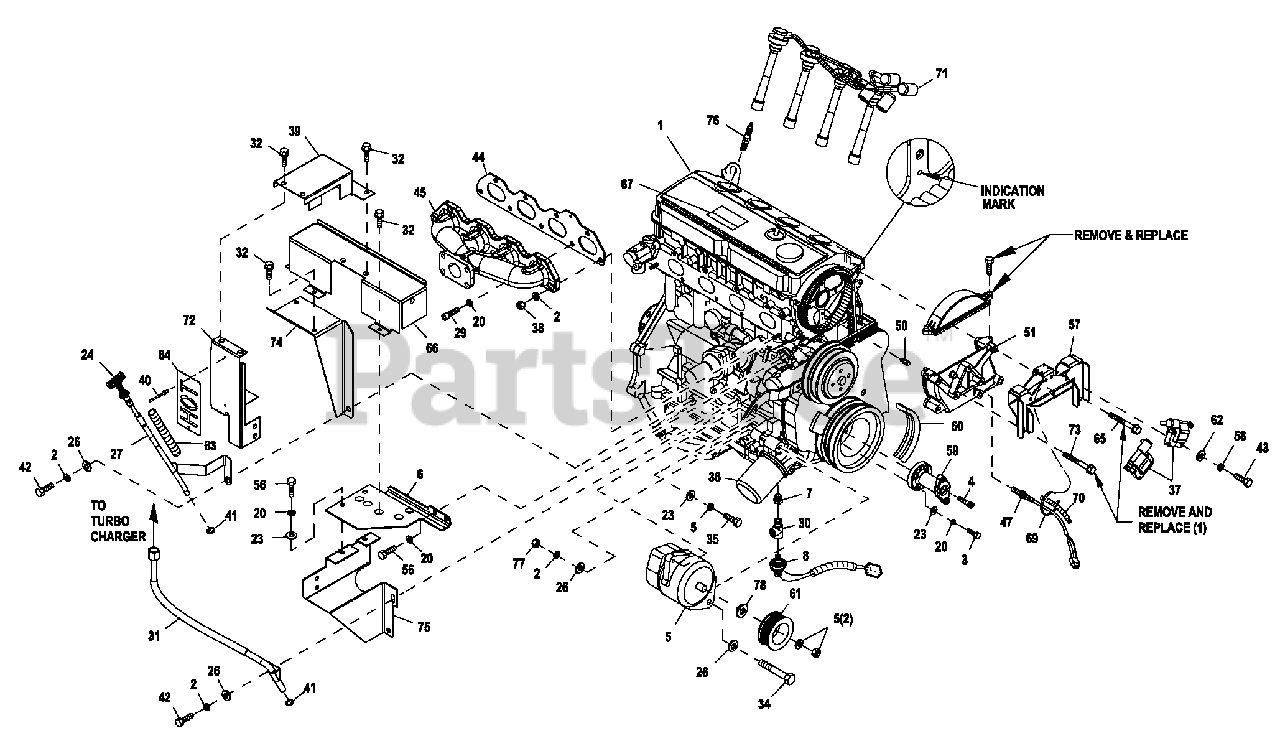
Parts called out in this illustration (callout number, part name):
1	ENGINE 2.4L G2 CERTIFIED
2	WASHER LOCK M10
3	SCREW HHC M8-1.25 X 35 G8.8
4	SCREW SHC M14-1.5 X 35 G10.9
5	ALTERNATOR DC W/O U T P ULLEY
6	U PR BRKT HEAT SHIELD 2.4L 36KW
7	ADAPTOR 1/8NPTF TO 1/8BSPT
8	SWITCH OIL PRESSU RE 10 PSI 2 POL (R-PANEL)
20	WASHER LOCK M8-5/16
23	WASHER FLAT 5/16-M8 ZINC
24	ASSEMBLY DIPSTICK G2.4L
26	WASHER FLAT 3/8-M10 ZINC
27	ASSY DIPSTICK TU BE 2.4 G2
29	SCREW SHC M8-1.25 X 25 G12.9
30	TEE STREET 1/8NPT BRASS W/VS
31	TU BE TU RBO OIL RETURN G2 36KW
32	SCREW HHTT M6-1.0 X 12 ZINC
34	SCREW HHC M10-1.5 X 120 C8.8
35	SCREW HHC M8-1.25 X 25 G10.9
36	FILTER 1.5L/2.4L G2 OIL
37	COIL-2.4L G2 IGNITION
38	N U T HEX M10-1.25 G8 YEL CHR
39	HEAT SHEILD INNER 2.4L G2 36K
40	RIVET POP .125 X 0.337 STEEL
41	O-RING SIZE 9.0MM X 2.0MM NITR
42	SCREW HHC M10-1.25 X 20 C8.8
43	SCREW HHM #10-32 X 1-1/4
44	GASKET EXHAU ST MANIFOLD
47	ASSY MAGPICK U P(3/8-24 MALE)
48	ADAPTER ENGINE 2.4L MACHINE
51	COVER CAM GEAR G2 REWORKED
56	SCREW HHC M8-1.25 X 16 C8.8
57	BRACKET ASM-2.4L COIL G2
58	WASHER LOCK #10
59	ADAPTER 2.4L CRANKSHAFT MACH
60	BELT SERPENTINE 37.0" (1800 RPM)
61	P U LLEY DC ALTERNATOR (1800 RPM)
62	WASHER FLAT #10 ZINC
63	COND UIT THERMAL FLEX 13MM ID
64	PLATE "HOT"
65	SCREW HHC M8-1.25 X 70 G8.8
66	SHIELD-MANIFOLD 2.4L G2 36KW
67	DECAL SORE EPA CERTIFICATION
69	TIE WRAP U L 7.4"X .19" BLK
70	CONDUIT FLEX .25"ID
71	SPARK PL U G WIRE SET 2.4L G2 IG
72	HEAT SHIELD OU TER 2.4L G2 36K
73	SCREW HHC M8-1.25 X 65 C8.8
74	BRKT-EXH MANF 2.4L 36KW
75	LWR BRKT ASM HT SHIELD G2 36KW
76	PLUG SPARK
77	NUT HEX M10-1.5 G8 YEL CHR
78	SPACER DC ALTERNATOR PULLEY
